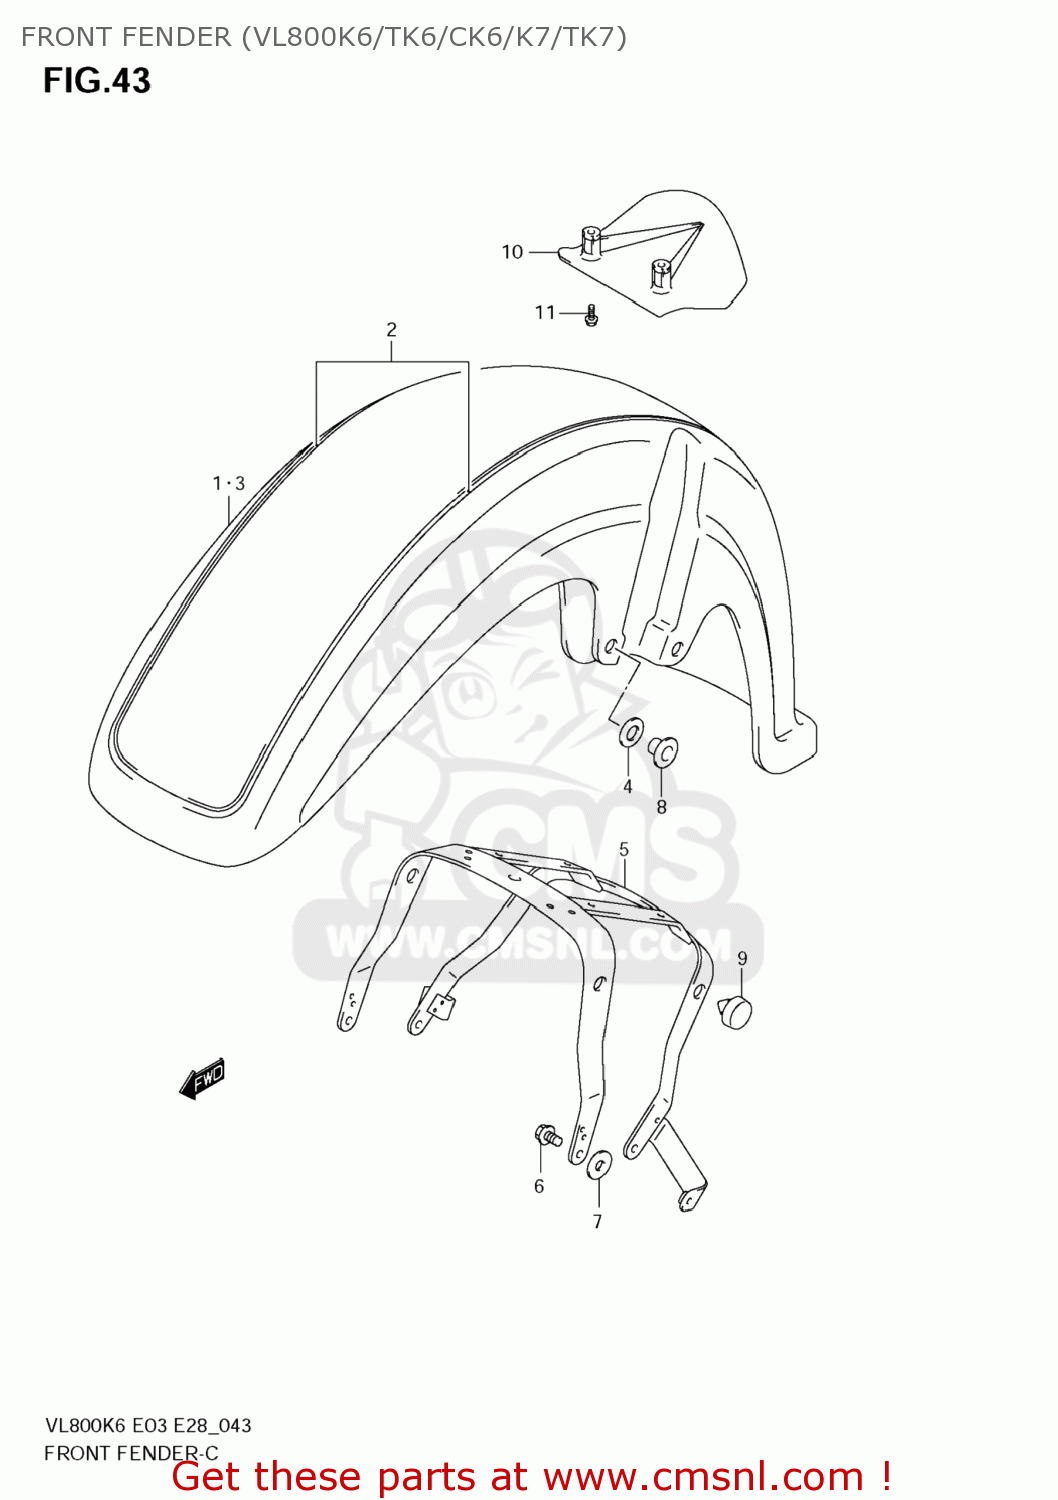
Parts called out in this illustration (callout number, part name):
1	FENDER,FR
2	TAPE SET,FR FENDER
3	FENDER,FR
4	CUSHION,FR FENDER
5	BRACE,FR FENDER
6	BOLT
7	WASHER,FR FENDER
8	WASHER,FR FENDER
9	CUSHION
10	WING,FR
11	BOLT(6X16)
